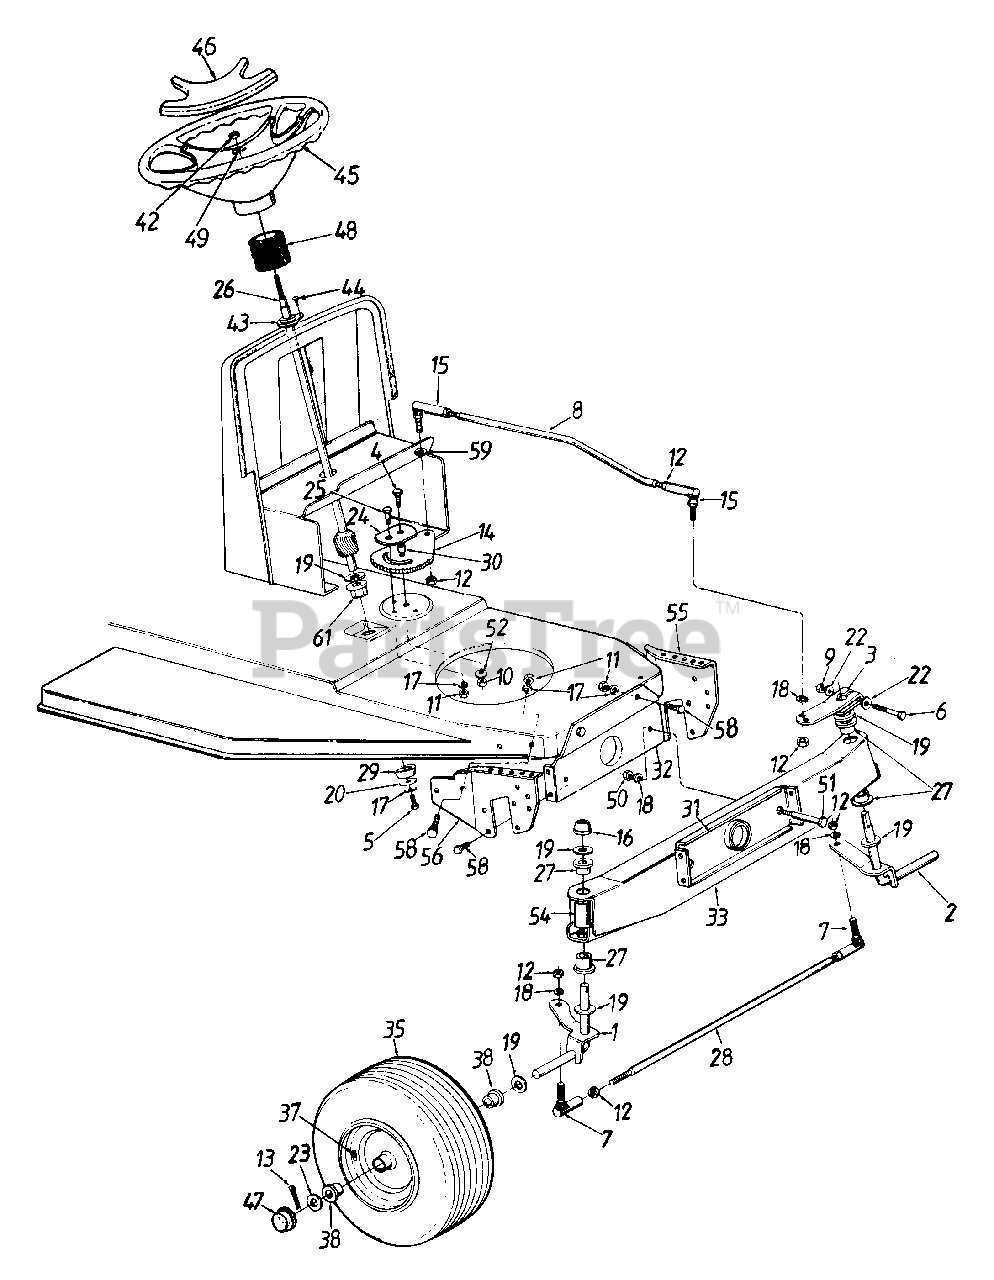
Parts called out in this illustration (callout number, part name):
1	Front Axle Ass'y. - R.H.
2	Front Axle Ass'y. - L.H.
3	Steering Arm
4	Hex Bolt 3/8-24 x 1" Lg.
5	Hex Bolt 5/1 6-18 x .62" (Spec.)
6	Hex Bolt 5/16-24 x 2" Lg.
7	Ball Joint 3/8-24 Thd.
8	Steering Drag Link
9	Hex L-Nut 5/16-24 Thd.
10	Hex Nut 3/8-24 Thd.
11	Hex Nut 5/16-18 Thd.
12	Hex Jam Nut, 3/8-24 Thd.
13	Cotter Pin 1/8 Dia.
14	Steering Gear Segment
15	Drag Link Ball Joint 3/8-24 Thd.
17	L-Wash. 5/16" I.D.
18	L-Wash. 3/8" I.D.
19	Fl-Wash. .64" I.D. x 1.24"
20	Fl-Wash. .340" I.D. x 1.125"
22	Spr. Wash. .32" I.D. x .62"
23	Fl-Wash. .635" I.D. x 1.585"
24	Retainer Plate
25	Shld. Bolt .437" Dia. x .350"
26	Steering Shaft
27	Hex Flange Brg. .632" I.D.
28	Tie Rod 20" Lg.
29	Spacer .985" I.D.
30	Spacer .380" I.D.
37	Air Valve
38	Bearing
42	Hex L-Nut 5/16-24 Thd.
43	Steering Column Brg.
44	Cr-Sunk Scr. #10 x 5/8" Lg.
45	Steering Wheel
46	Steering Wheel Cap
47	Hub Cap
48	Bellow Steering Column
49	Bell-Wash. .345" I.D. x .88"
50	Hex Nut 3/8-16 Thd.
51	Shld. Bolt 1/2" Dia. x 2.04"
52	Bell-Wash. .39" x 1.38" O.D.
54	Plastic Tube
55	Pivot Bar Side Plate - L.H.
56	Pivot Bar Side Plate - R.H.
58	Hex Wash. Tap Scr. 5/16-18 x .62" Lg.
59	L-Wash. 3/8" I.D. (H.D.)
61	Hex Flange Brg. .634" Dia.
